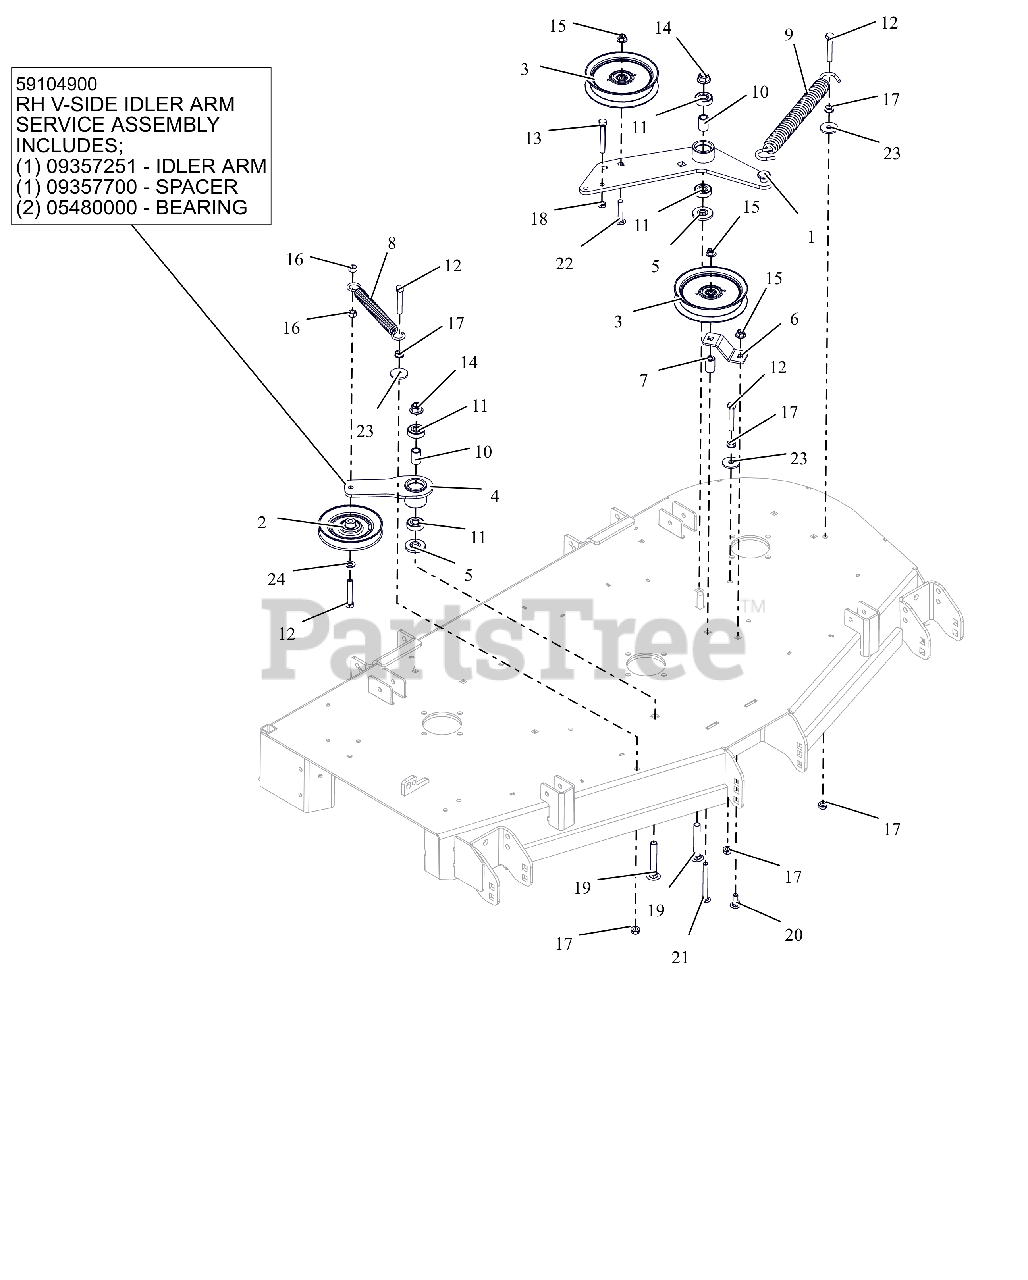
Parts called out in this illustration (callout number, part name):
1	DECK PTO IDLER ARM WLDMT - BLK
2	IDLER, V-5.00"
3	IDLER, FLAT 5.00"
4	DECK RH IDLER ARM WMT - BLK
5	SPACER, IDLER ARM
6	PTO FIXED IDLER MTG BRKT -RED
7	BUSHING, SLV .380X.750X1.190
8	SPRING, EXTENSION
9	SPRING, EXTENSION
10	SPACER .510 X .75 X 1.1485
11	BRG-BALL .500X1.38X.437
12	BLT,HEX .38-16X2.25 G5 ZCC
13	BLT, HEX .38-16X2.75 G5 ZCC
14	NUT,NYL-FLG .50-13 GF ZCC
15	NUT,NYL-FLG .38-16 GF ZCC
16	NUT-LK-CTR .38-16 ZC120
17	NUT, SPNLK-FLG .38-16 G5 ZCC
18	NUT-JAM .375-16 G2 ZCC
19	BTL,RHSSN .500-13 X 3.25 G5 ZCC
20	BLT,RHSSN .38-16X1.00 G5 ZCC
21	BLT,RHSSN .38-16X3.50 G5 ZCC
22	BLT,RHSSN.375-16X2.00 G5 ZCC
23	WSHR,FLT .406X1.375X.135 ZCC
24	WSHR,FLT .406X.812X.065 ZCC
